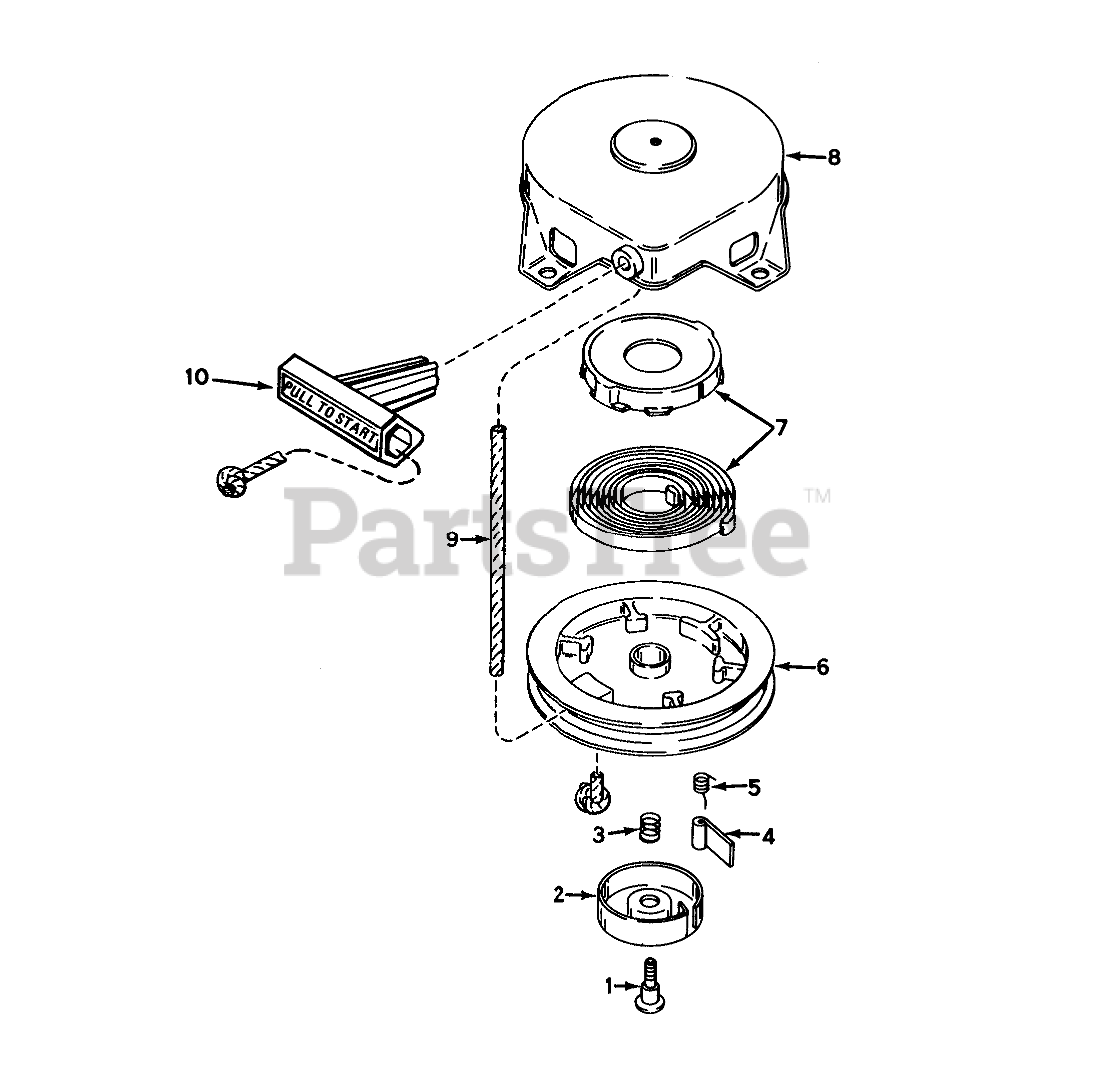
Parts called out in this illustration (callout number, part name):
2	Retainer
3	Spring-Brake
4	Dog-Starter
5	Spring-Dog
6	Pulley
7	Spring & Keeper Assy
8	Housing-Starter
9	Rope-Starter (98 cut to length)
10	Handle-Starter
